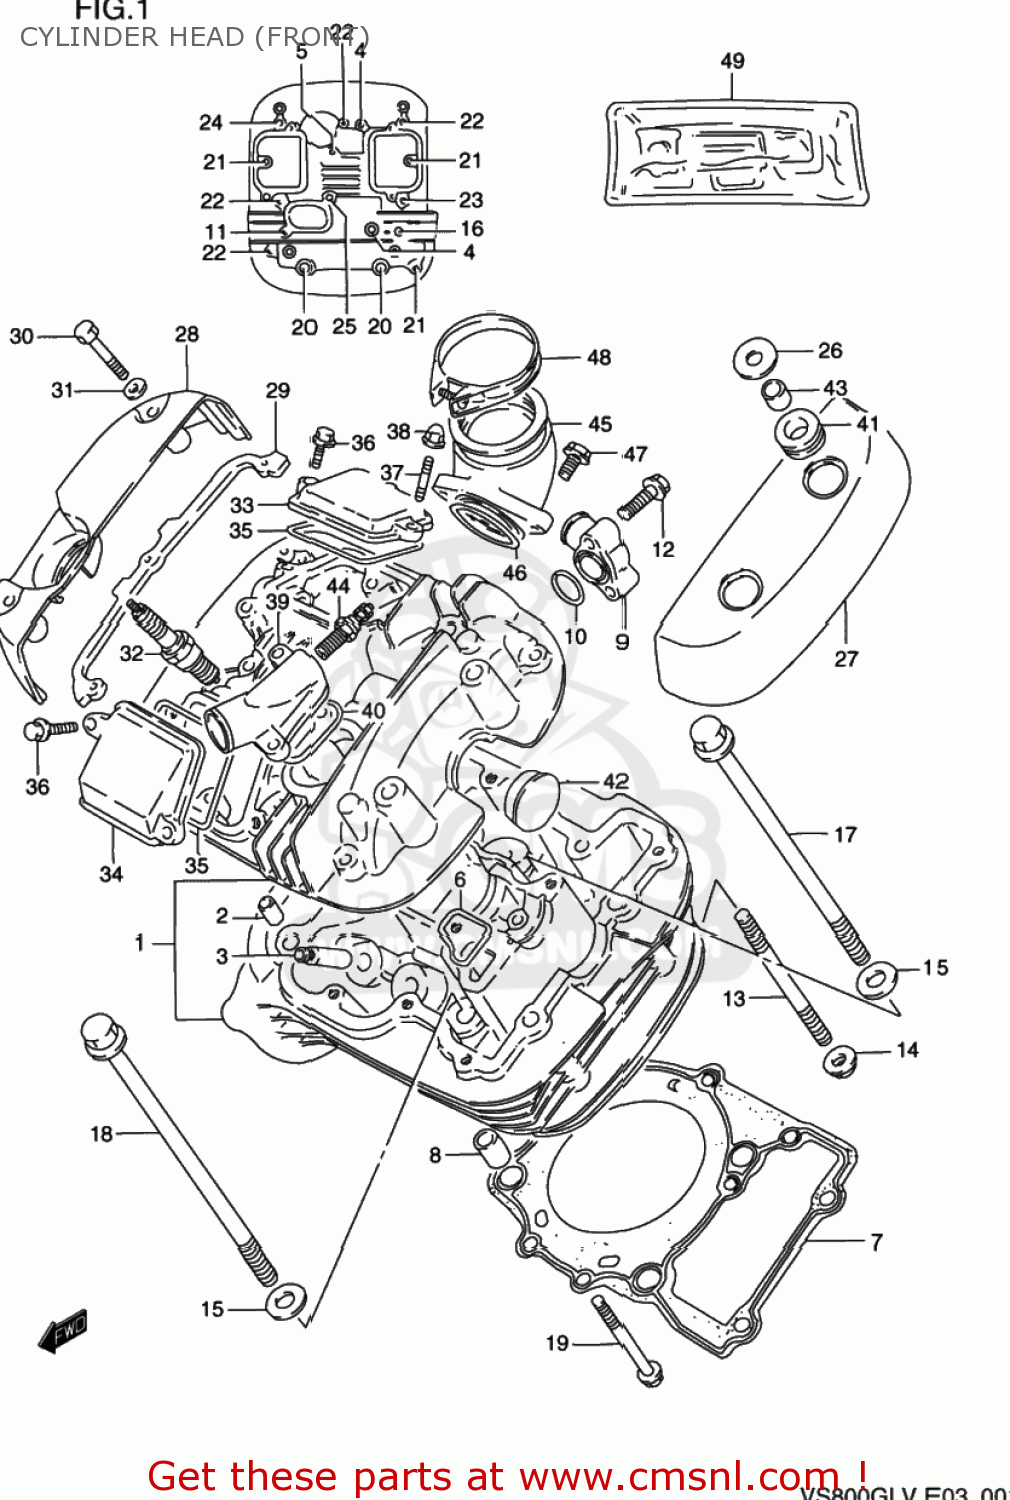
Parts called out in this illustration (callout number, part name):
1	HEAD ASSEMBLY,CYLINDER,FRONT
2	GUIDE,VALVE
3	PIN(11X14)
4	BOLT(6X50)
5	BOLT(6X55)
6	GASKET,CYLINDER HEAD WATER (NAS)
7	GASKET,CYLINDER HEAD FR (NAS)
8	PIN
9	UNION,CYLINDER HEAD WATER
10	O RING(D:2.4,ID:17.8)
11	BOLT
12	BOLT
13	BOLT,STUD
14	NUT
15	WASHER(10.5X22X2.3)
16	BOLT(8X140)
17	BOLT(10X155)
18	BOLT(10X165)
19	BOLT
20	BOLT(8X245)
21	BOLT
22	BOLT
23	BOLT
24	BOLT
25	BOLT(6X55)
26	WASHER (8.2X24X1.6)
27	CAP,CYLINDER HEAD COVER FR,L
28	CAP,CYLINDER HEAD COVER FR,R
29	CUSHION,FR,R CAP
30	BOLT
31	WASHER
32	PLUG,SPARK(DPR8EA-9)
33	CAP,INSP.INT
34	CAP,INSPECTION,EXHAUST
35	GASKET,INSPECTION CAP (NAS)
36	BOLT
37	STUD 6X16
38	NUT
39	UNION
40	GASKET,WATER OUTLET UNION (NAS)
41	CUSHION
42	PLUG
43	BUSH
44	GAUGE ASSY,WATER TEMP
45	PIPE,INTAKE
46	O-RING (D:2.4 ID:39.7)
47	BOLT
48	CLAMP
49	GASKET SET (NAS)
